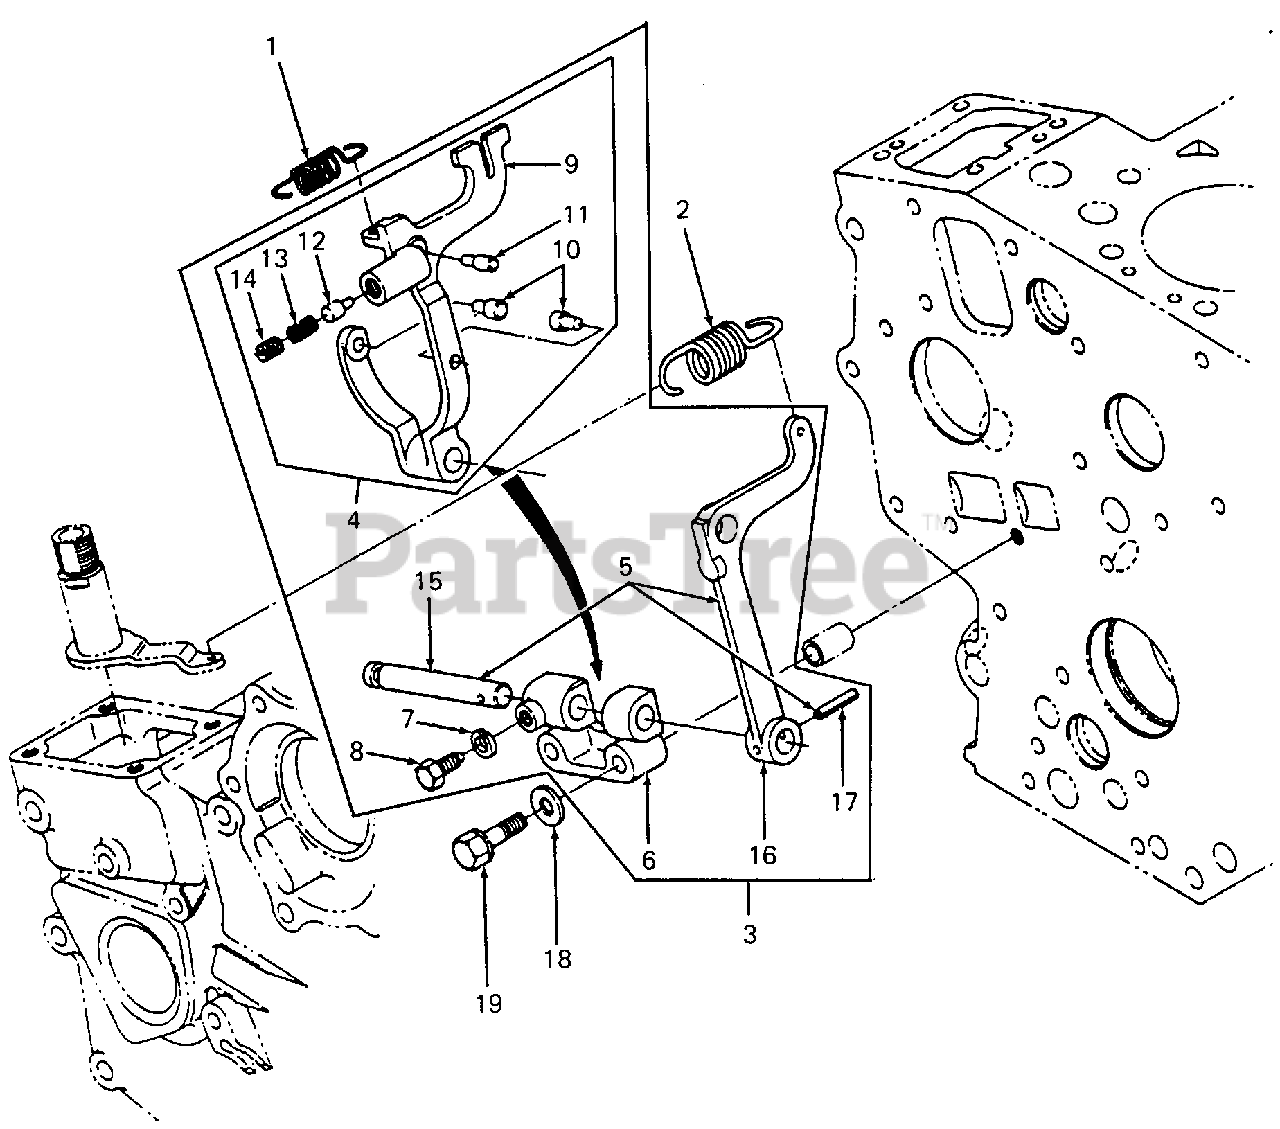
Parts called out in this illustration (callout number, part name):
1	Spring, Start
2	Spring, Governor
3	Fork Assy Complete
4	Lever Assy, Fork
5	Lever Assy, Fork
6	Holder, Fork Lever
7	Washer, Spring
15	Shaft, Fork Lever
